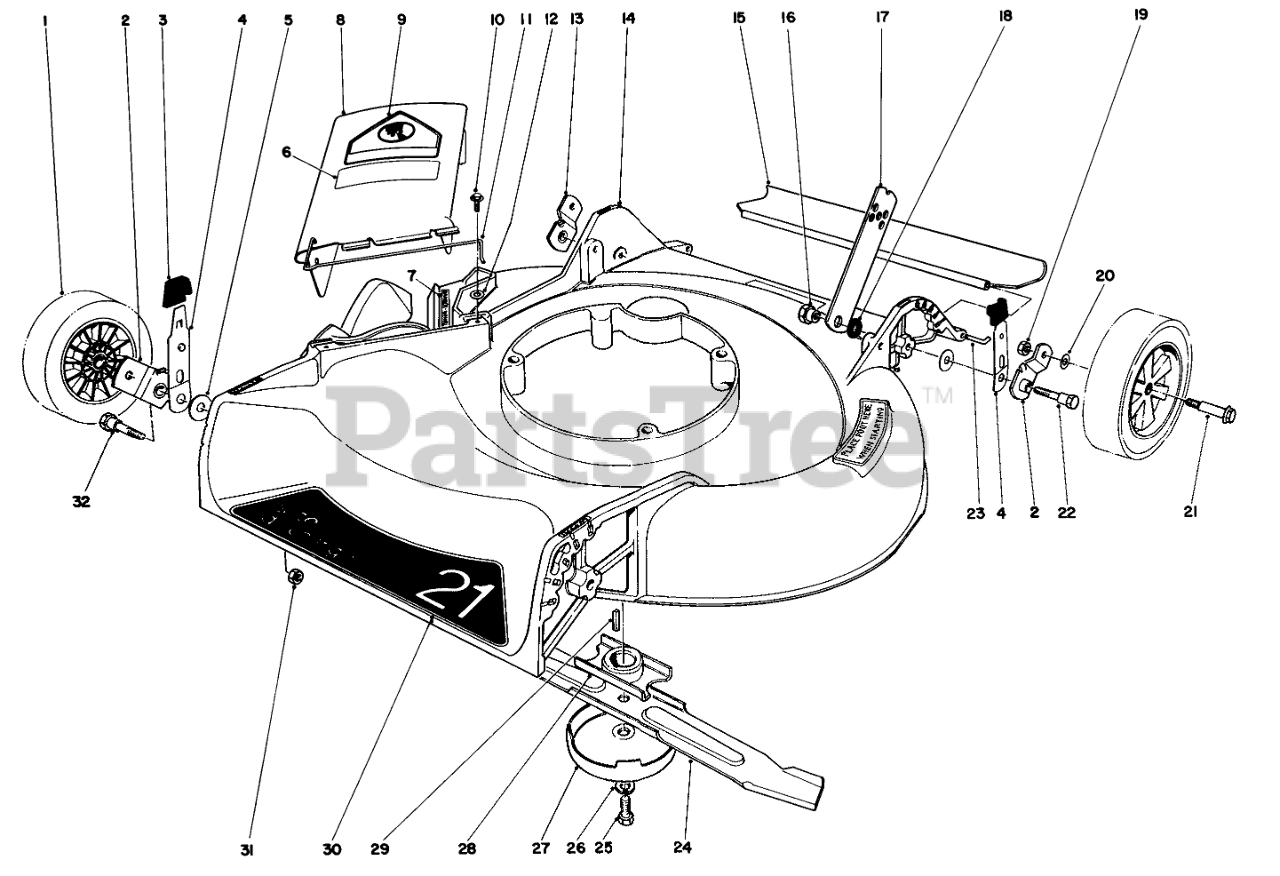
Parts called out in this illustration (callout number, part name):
1	WHEEL TIRE ASM 8 IN
2	Pivot Arm
3	KNOB-ARM
4	SPRING ARM ASM
5	WASHER-PIVOT
6	DECAL DEFLECTOR
7	Decal
8	Deflector-Cover Assembly (Incl. Ref. #6, 9 & 11)
9	DECAL-DANGER
10	SCREW
11	SPRING HINGE
12	WASHER-FLAT
13	Pivot Arm
14	Housing
15	Rear Shield
16	HANDLE PIVOT NUT
17	HANDLE LATCH
18	HANDLE LATCH SPACER
19	Nut
20	WASHER
21	BOLT-WHEEL
22	PIVOT SCREW
23	SHIELD ROD
24	Blade
25	SPECIAL SCREW
26	WASHER-LOCK
27	AntiScalp Cup
28	Blade Retailer
29	KEY-SQUARE
30	Decal-Side Discharge
31	Nut
32	PIVOT SCREW
